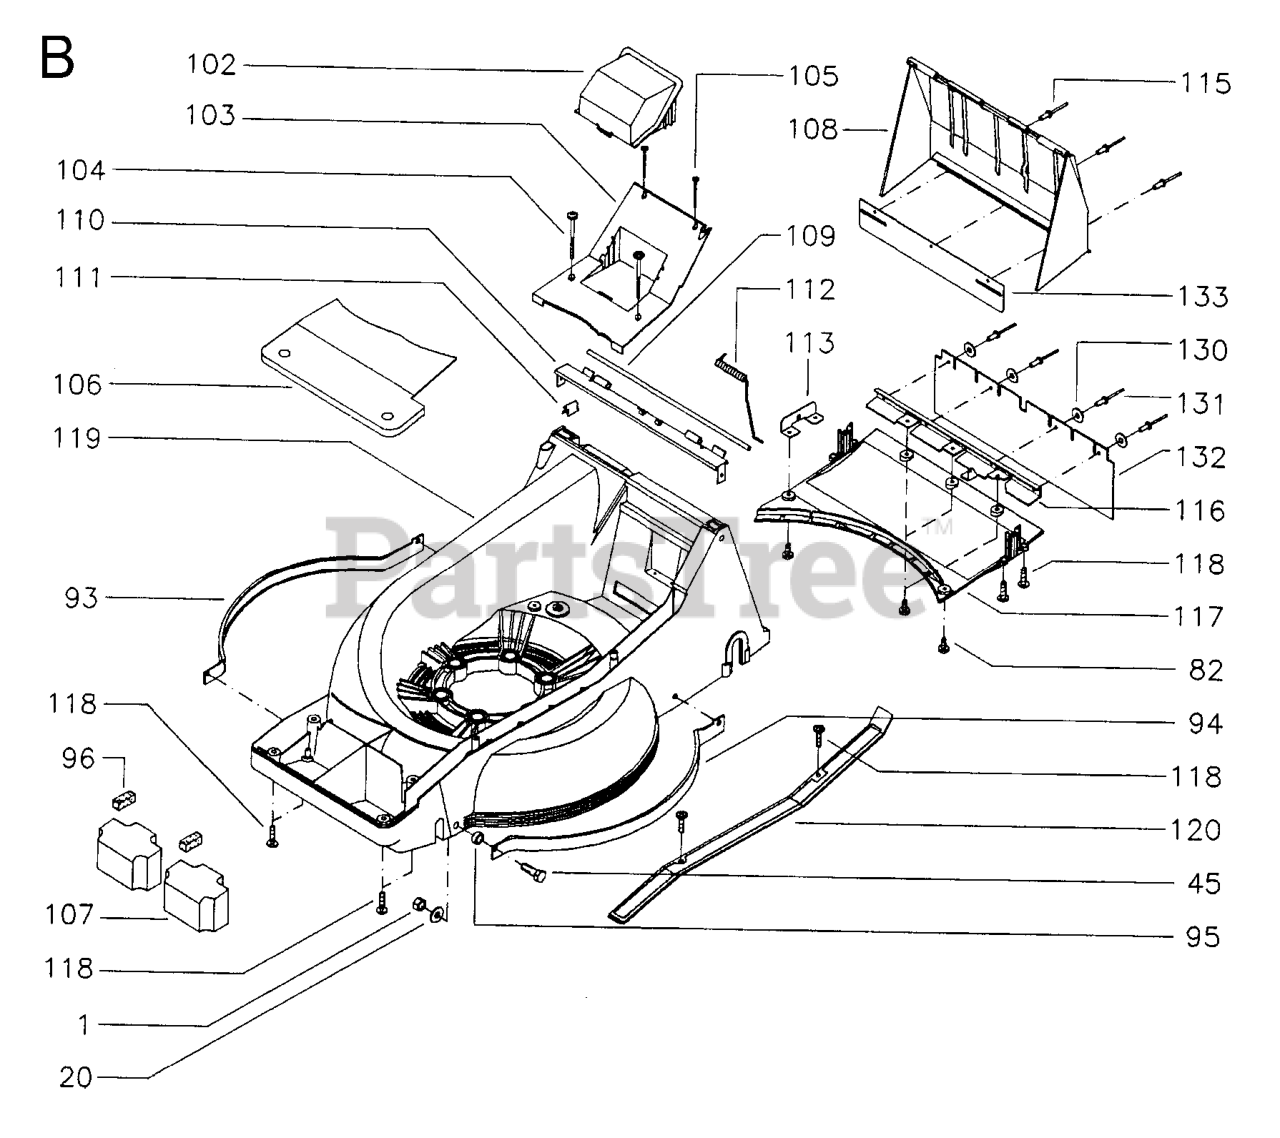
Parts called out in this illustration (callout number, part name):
1	LOCKNUT M8
45	SCREW M6S 8X25
93	DECK PROTECTOR RH
94	DECK PROTECTOR LH
106	DECK FRONT COVER
107	COUNTERWEIGHT
110	BRACKET
113	BRACKET
120	COVER
